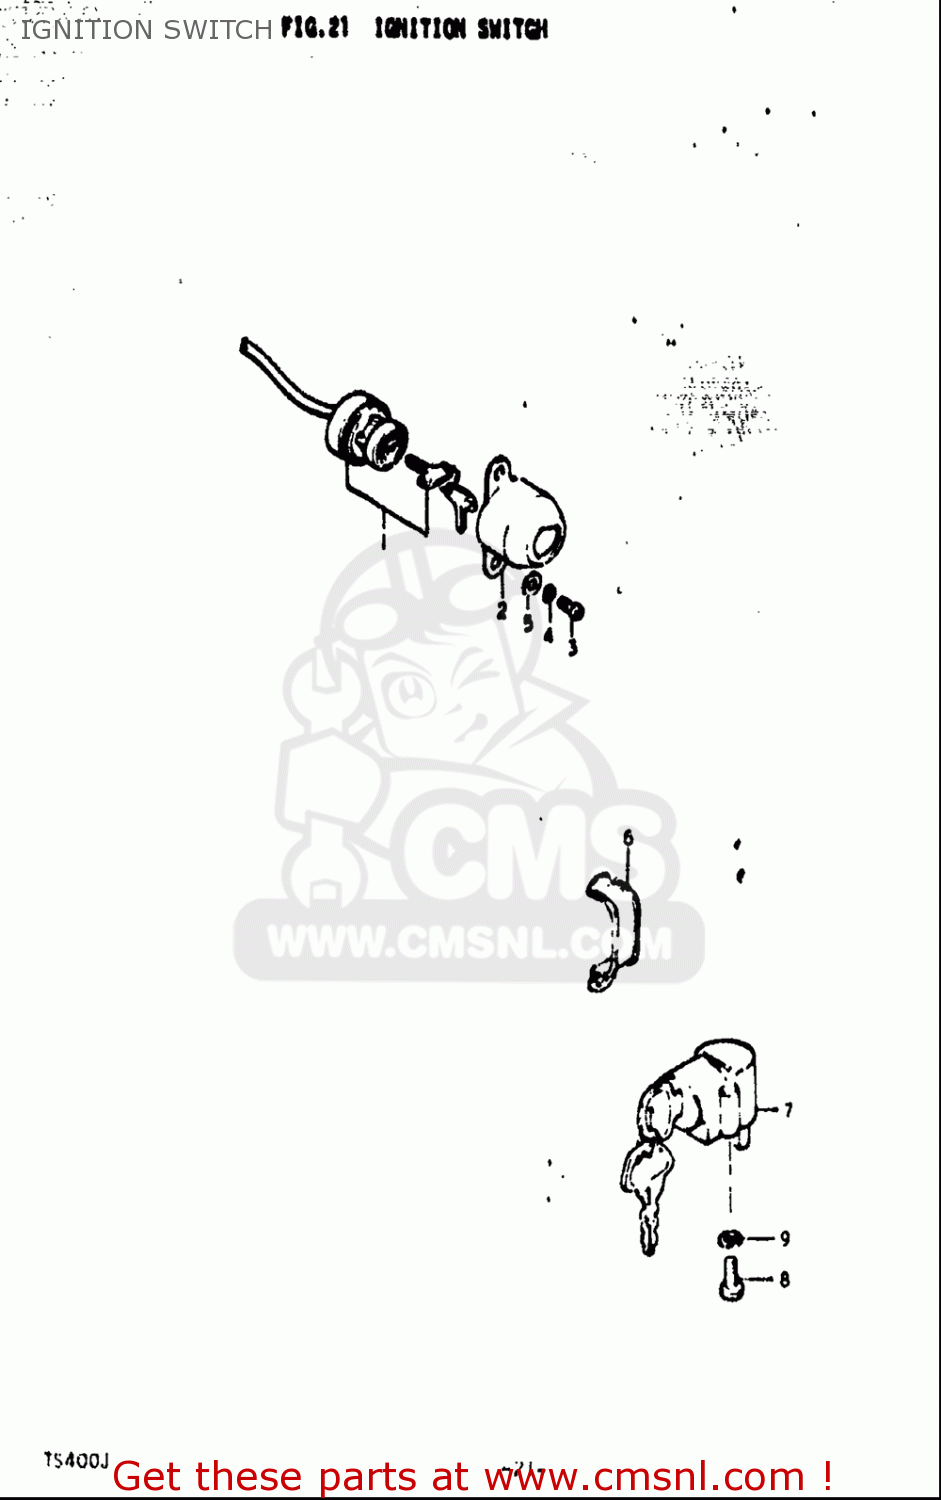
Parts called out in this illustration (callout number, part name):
3	SCREW
4	WASHER,LOCK
5	WASHER
6	CLAMP
7	LOCK ASSY,STEERING
8	SCREW
9	WASHER,LOCK
